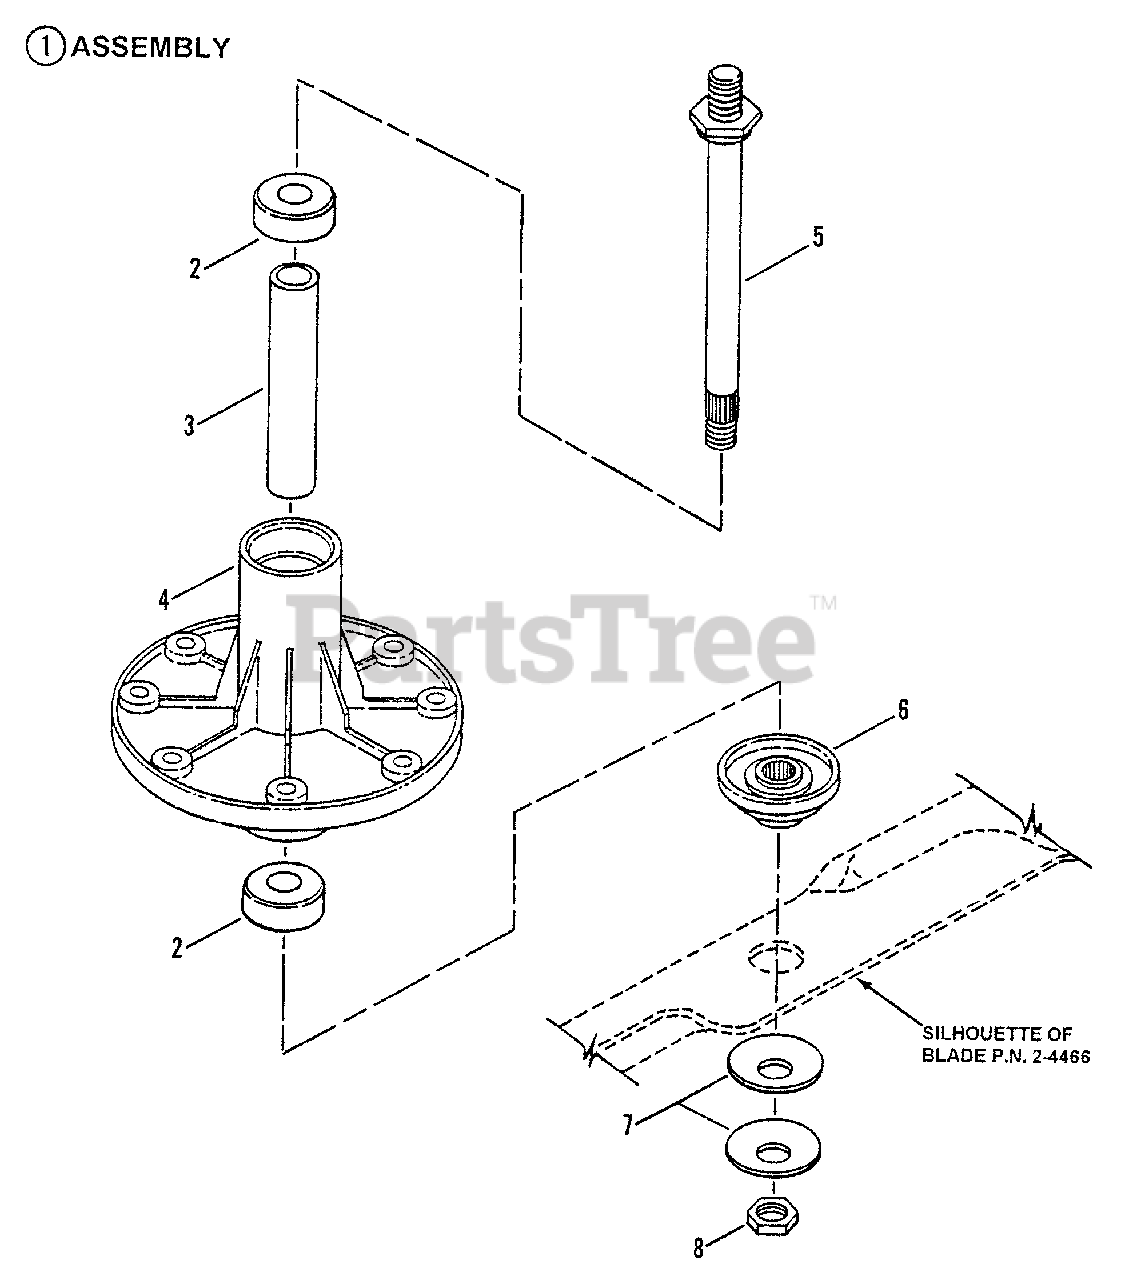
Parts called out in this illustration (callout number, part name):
1	ASSEMBLY, Spindle Housing, 38" Cutting Deck
2	BEARING, Spindle
3	SPACER, Spindle Housing
4	HOUSING, Spindle
5	SPINDLE 7.019"
6	SPACER, Dust Cover, Blade
7	WASHER, Belleville, 19/32" I.D. x 1-3/4" O.D.
8	NUT, 9/16-18 Hex Jam, Grade B
